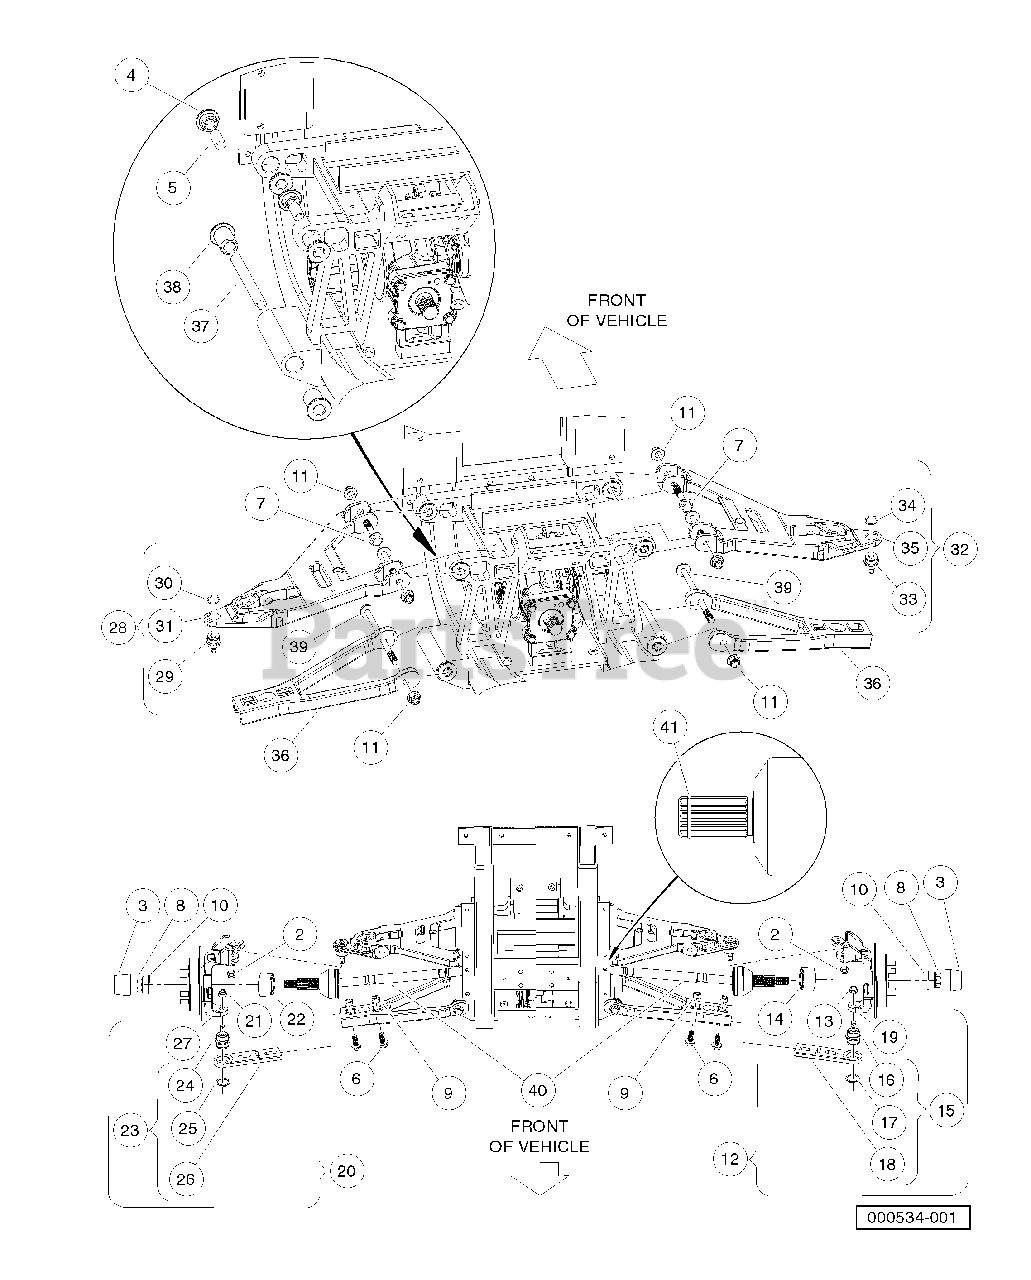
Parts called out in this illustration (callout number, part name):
1	Suspension, AWD, Wide
2	Locknut, M12-1.25 Nylon
3	Center Cap, Rubber
4	Bushing, A-Arm
5	Sleeve, Upper
6	Bolt, Flange Head, M12x 1.75x 30 with Loctite
7	Bolt, Flange Head, M12 X 1.75 X 70
8	Nut Flg, M22 X 1.5 Mech Def
9	Nut, Square, M12x 1.75
10	Washer Hard, M22
11	Nut Flg, M12x1.75, Nylon Gr 10
12	Upright, Left-Hand
13	Locknut, M12-1.25 Nylon
15	Asm, Adjuster, Slide
16	Joint, Ball
17	Ring, Retaining, Ext, 1-1/4"
18	Slide, Adjuster
19	Upright, Finished, Lh
20	Upright, Right-Hand
21	Locknut, M12-1.25 Nylon
23	Asm, Adjuster, Slide
24	Joint, Ball
25	Ring, Retaining, Ext, 1-1/4"
26	Slide, Adjuster
27	Upright, Finished, Rh
28	Asm, A-Arm, Upper, Left
29	Joint, Ball
30	Ring, Retaining, Ext, 1-1/4"
31	Arm, Upper, Wide, Machined, Lh
32	Asm, A-arm, Upper, Right
33	Joint, Ball
34	Ring, Retaining, Ext, 1-1/4"
35	Arm, Upper, Wide, Machined,rh
36	A-Arm, Lower
37	Sleeve, Lower Arm
38	Bushing, Lower Arm
39	Bolt Flg, M12 X 1.75 X 200 10
40	Half Shaft, Wide, Awd
41	Ring, Hog, Half Shaft
